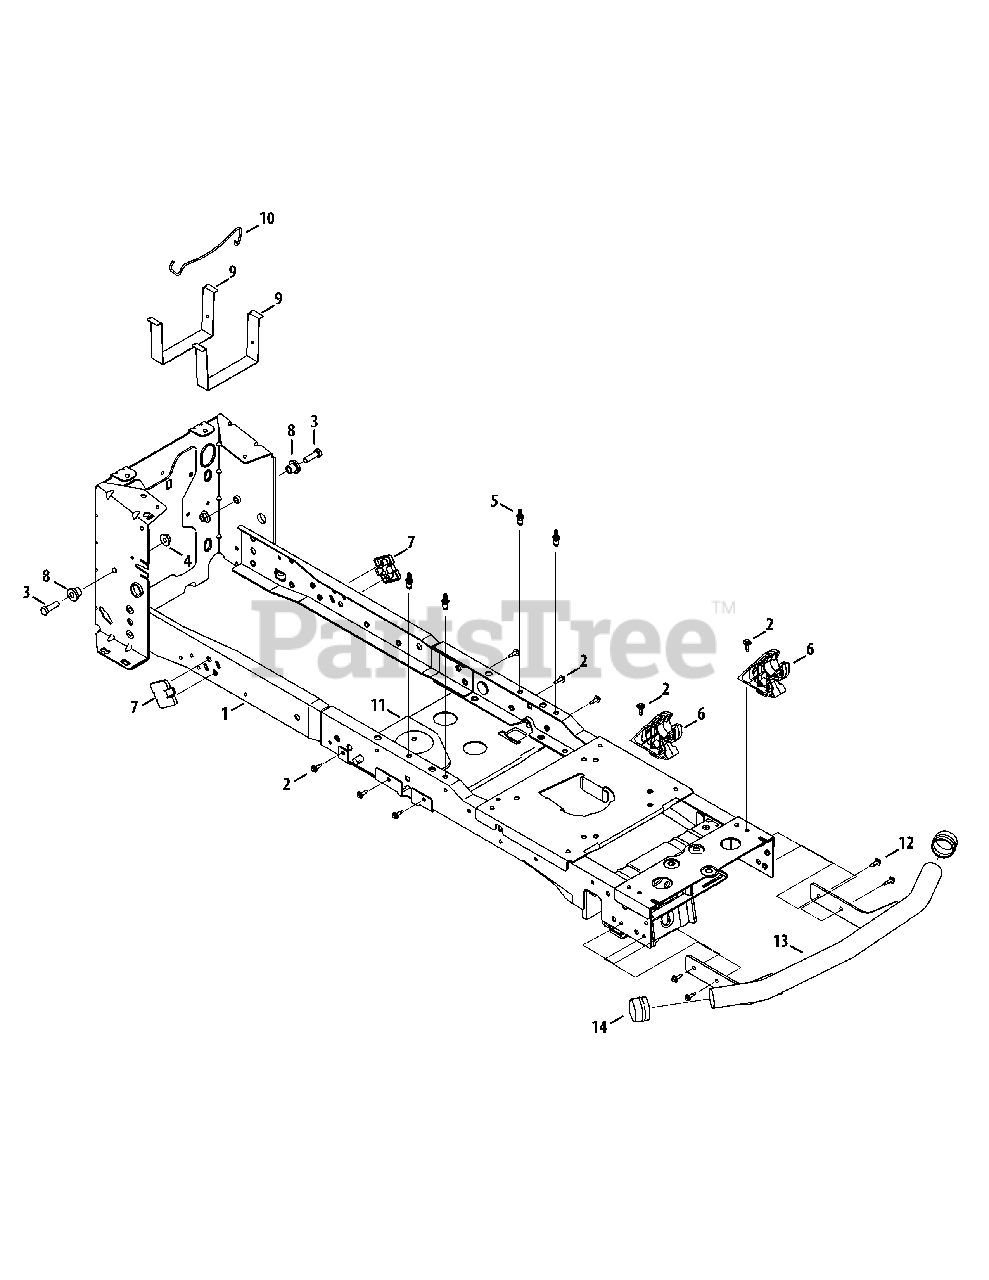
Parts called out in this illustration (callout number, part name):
1	Frame Assembly
2	Screw, M6-1 x .625
3	Hex Cap Screw, 3/8-16 x 1.25
4	Flange Lock Nut, 3/8-16
5	Rivet, 1/4-20 x .750
6	Pivot Bracket
7	Wear Pad
8	Shoulder Spacer, .38 x 1.0 x .70
9	Battery Bracket
10	Rod, Battery
12	Hex Flange Screw, 3/8-16
13	Bumper Assenbly
14	Hub Cap
